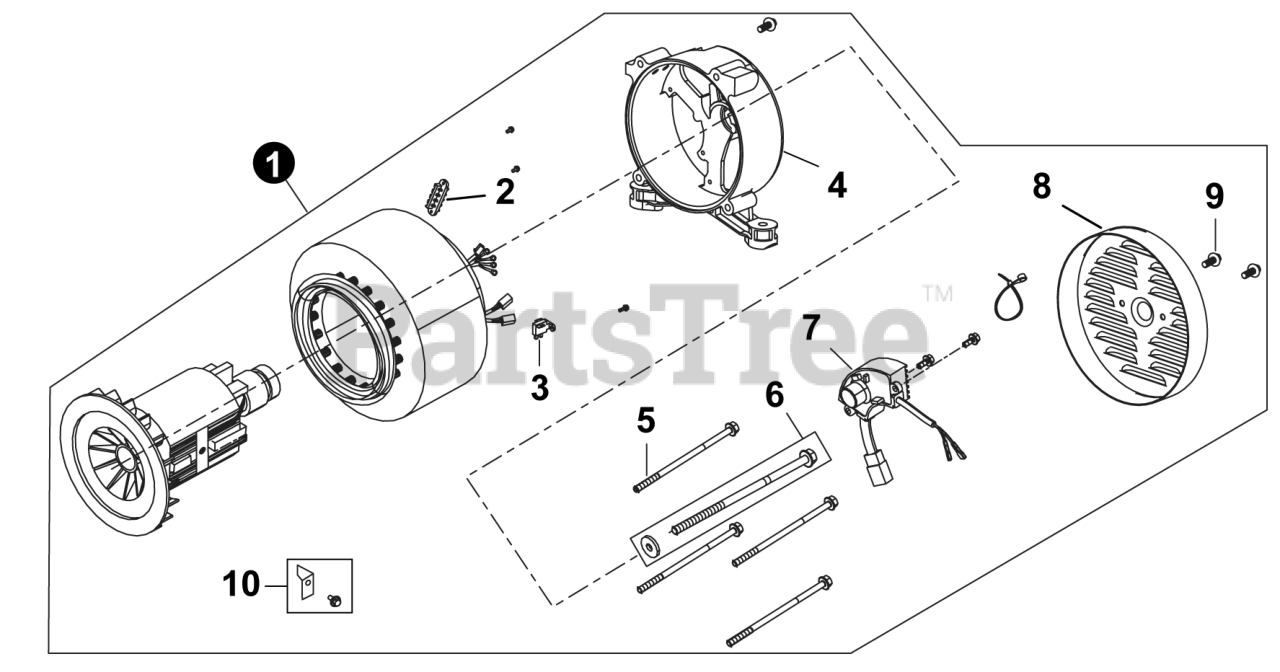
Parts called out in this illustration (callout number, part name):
1	GENERATOR ASSY.
2	BLOCK, TERMINAL
3	BRUSH, CARBON
4	BRACKET, MOTOR
5	BOLT, STATOR
6	BOLT, ROTOR
7	REGULATOR, VOLTAGE
8	COVER, MOTOR TAIL
10	STOPPER, MOTOR RIGHT COVER
